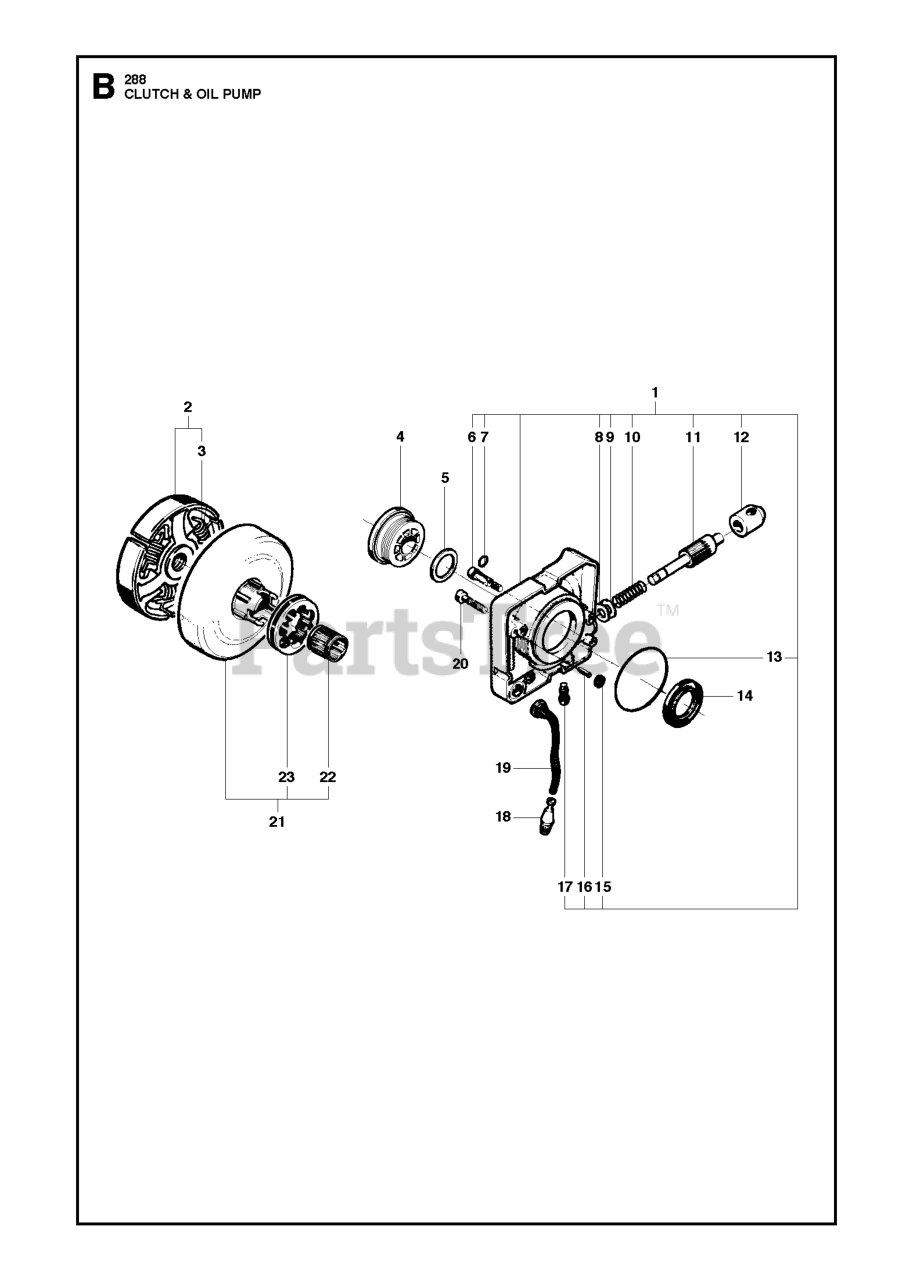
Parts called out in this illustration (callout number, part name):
3	CLUTCH SPRING
8	WASHER 6.6X11
9	WASHER 6.6X11
11	PUMP PISTON
14	SEALING RING
16	SPRING PIN 3X6
17	CONTROL SCREW
18	OIL SCREEN
20	SCREW MC6S 4X20
21	CLUTCH DRUM
22	SUPPORT BUSHING
23	68210 RIMSPROCKET
23	22270 RIMSPROCKET
